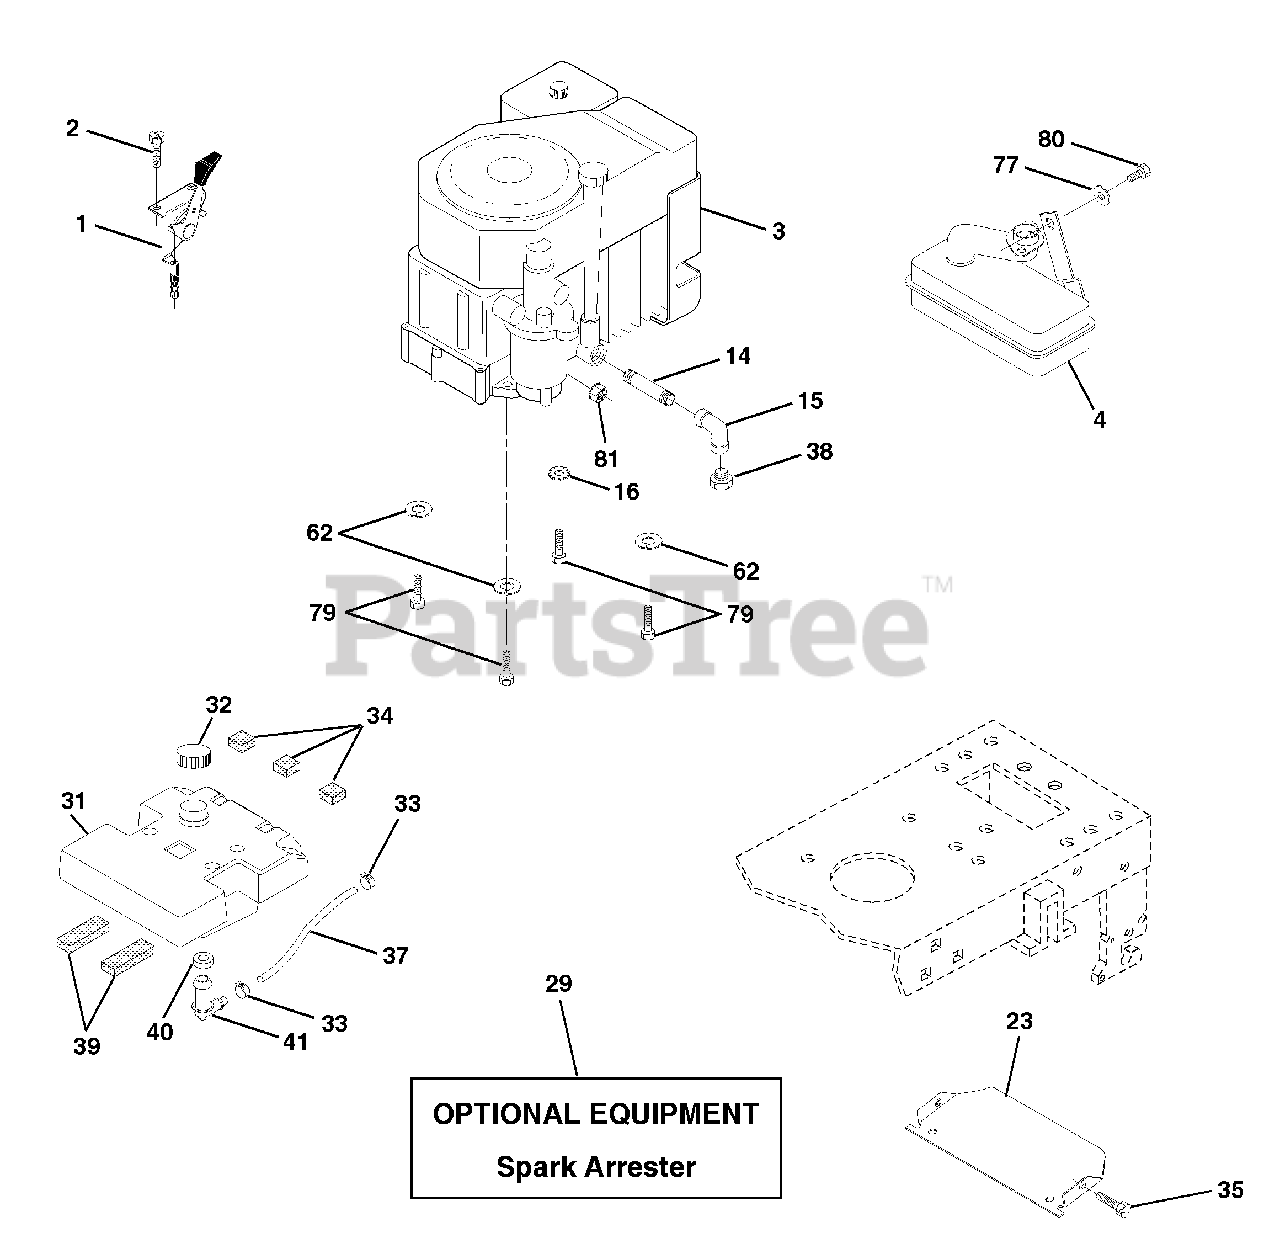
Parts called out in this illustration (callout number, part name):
1	Control Th/ch 27. LH. Flag Dom.
2	Screw Hex Thd Cut 1/4-20x5/8 T
4	Muffler LT Kohler 12.5/15HP
14	Nipple Pipe 3/8 Npt X 3-1/2
15	Elbow Std 90 Degree 3/8-18 Npt
16	Washer Lock Ext Tooth 5/16
23	Shield Heat
29	Kit Spark Arrestor (Flat Scrn)
31	Tank Fuel 3.5 STLT W/O Sensor
32	Cap Asm Fuel W/sym Vented
33	Clamp Hose Black
34	Pad Spacer
35	Screw
37	Line Fuel 7.5"
38	Plug Oil Drain
39	Pad Idler 1.75 x .75 x .06
40	Bushing
41	Stem Tank Fuel
62	Washer Lock Hvy Hlcl Spr 5/16
77	Washer 5/16 x 3/4 x 16 Ga.
79	Bolt Hex
80	Bolt Hex Hd. 5/16-18unc x 1/2
81	Nut Flange 1/4-20 Starter Nut
